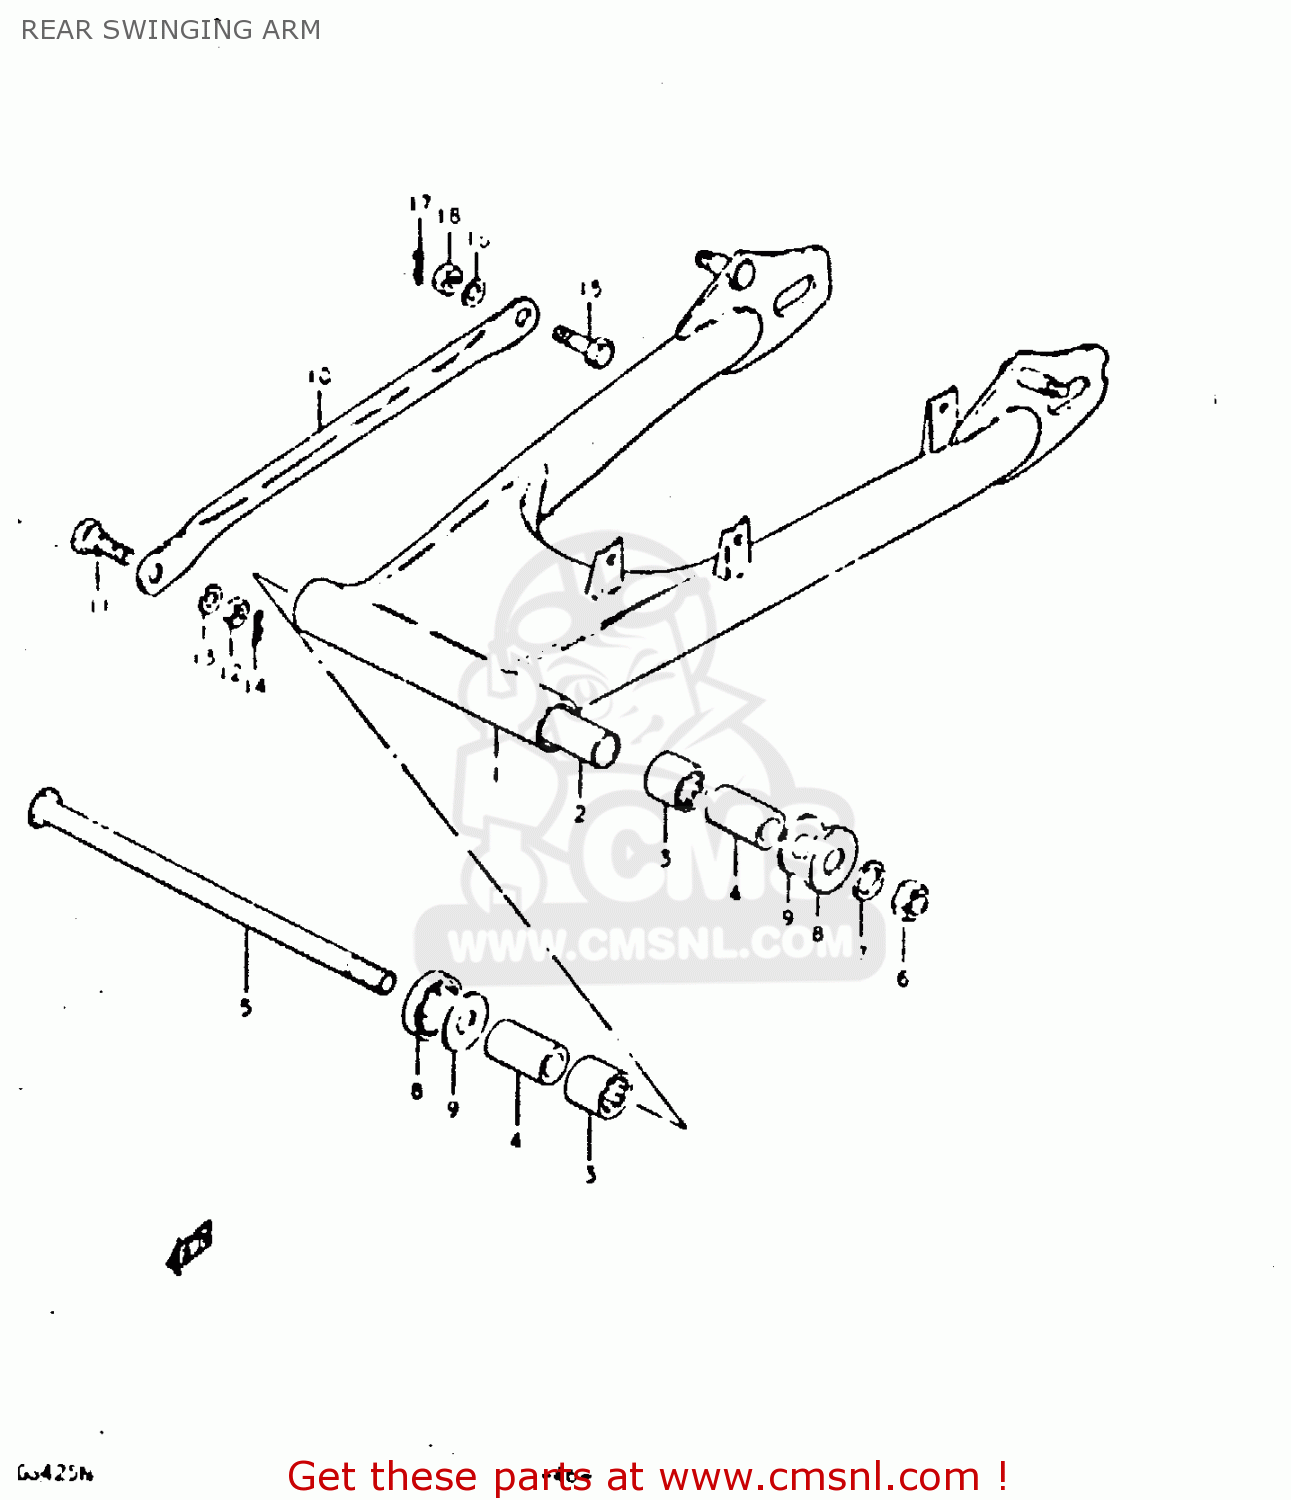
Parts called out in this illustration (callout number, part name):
1	SWING ARM ASSEMBLY,REAR
2	SPACER,RR SWGARM PIVOT
3	BEARING(22X29X30)
4	SPACER,SWINGINGARM CTR
5	SHAFT,REAR SWING ARM
6	NUT 14MM
7	WASHER
8	CVR,RR SWGARM DUST SEAL(OD:40)
9	WASHER(14.2X34X1)
10	TORQUE LINK,REAR
11	BOLT(10X24.5)
12	NUT
13	LOCK WASHER
14	CLIP
15	BOLT(10X31)
16	LOCK WASHER
17	CLIP
18	NUT
